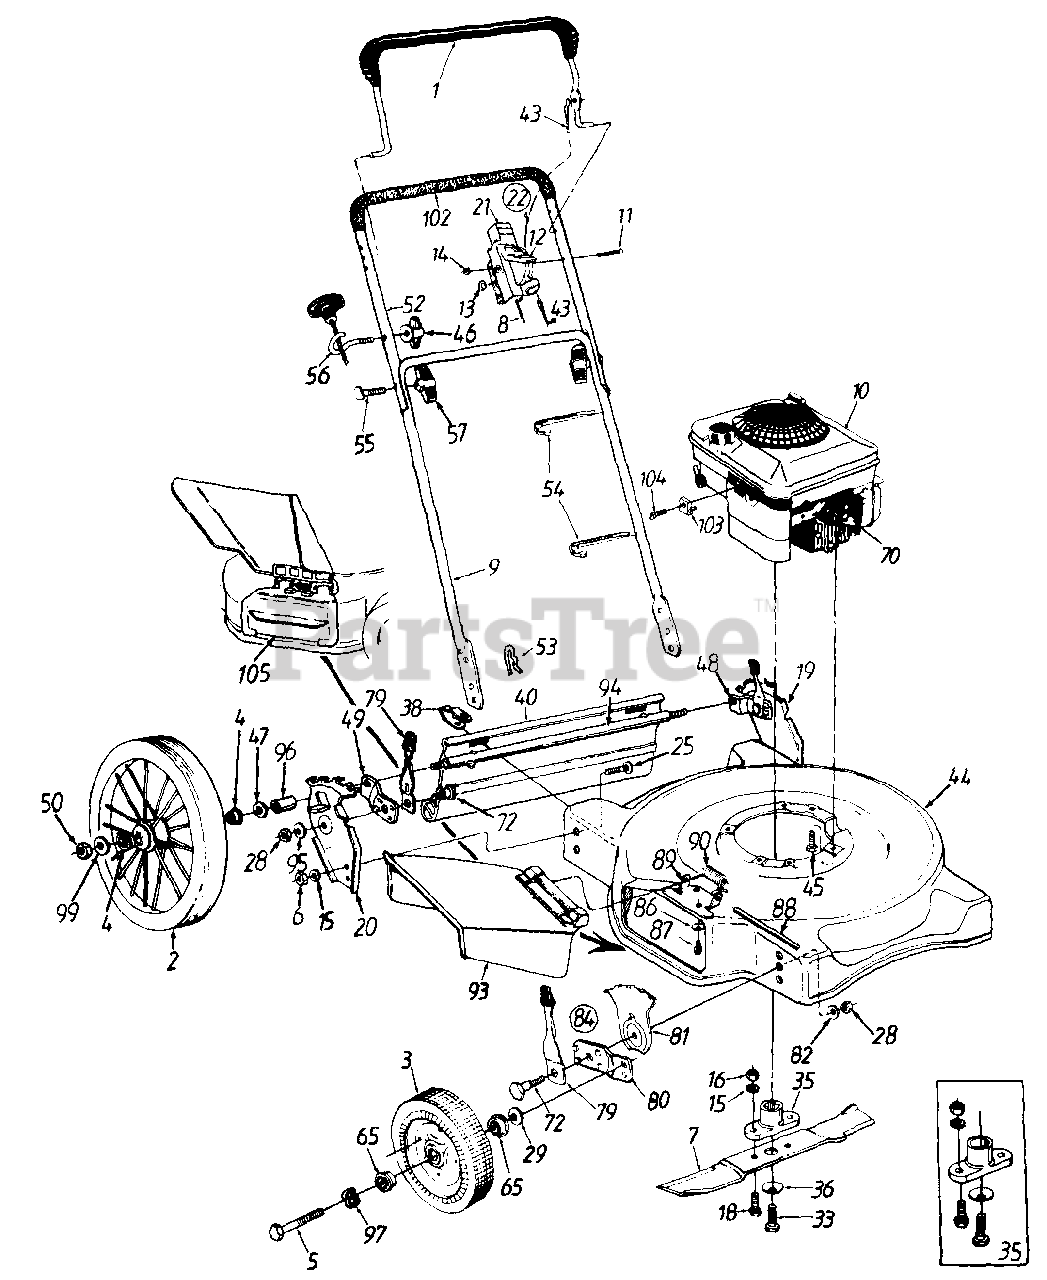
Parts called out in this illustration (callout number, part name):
1	Control Handle
2	16" Wheel Ass'y.
3	Front Wheel Ass'y.
4	Bearing 1/2" I.D.
5	Front Axle Bolt
6	Hex Nut 3/8-24 Thd. (Gr. 8)
7	22" Blade
8	Throttle Control Wire - 51"
10	Engine
11	Oval C-Sunk Mach. Scr.
12	Throttle Lever
13	Spr. Wash. .66" I.D.
14	Hex L-Nut 1/4-20 Thd.
15	L-Wash. 3/8" I.D.
16	Hex Nut 3/8-24 Thd.
18	Hex Bolt 3/8-24 x 1.0" Lg.
22	Throttle Box Comp.
25	Ribbed Neck Bolt 3/8-24 x .80"
28	Hex Nut 3/8-16 Thd.
29	Bell-Wash. .400" I.D. x .88"
33	Hex Bolt 3/8-24 x 1.5" Lg.
35	Blade Adapter Kit
36	Bell-Wash. .39" I.D.
38	Hinge Clip
40	Rear Flap Ass'y.
43	Control Cable - 39"
46	Wing Nut 1/4-20 Thd.
47	Wave Wash. .51" I.D.
48	Small Pivot Bar - L.H.
49	Small Pivot Bar - R.H.
50	Hex Jam Nut 3/8-16 Thd.
54	Cable Tie
55	Curved Hd. Bolt 5/16-18 x 2" Lg.
57	Hand Knob
65	Bearing
70	Spark Plug Boot
72	Shoulder Bolt .50" Dia.
79	Spring Lever Ass'y. w/Knob
81	Height Adj. Plate
82	Bell-Wash. .39" I.D. x 1.38"
84	Front Height Adj. Ass'y. Comp. - R.H.
86	Bell-Wash. .285" I.D. x .75"
87	Hex Wash. Hd. Tap Scr. 1/4-20 x .5" Lg.
88	Hinge Pin
89	Adapter Plate
90	Torsion Spring
93	Chute Deflector Ass'y. Comp.
95	Bell-Wash. .39" I.D. x 1.13"
96	Spacer .55" I.D. x .75"
97	Wave Washer .51" I.D.
99	Fl-Wash. .406" I.D. x .81"
102	Foam Grip
103	Casing Clamp
104	Hex Wash. Hd. Tap Scr. #10-32 x .62" Lg.
105	Mulching Baffle
